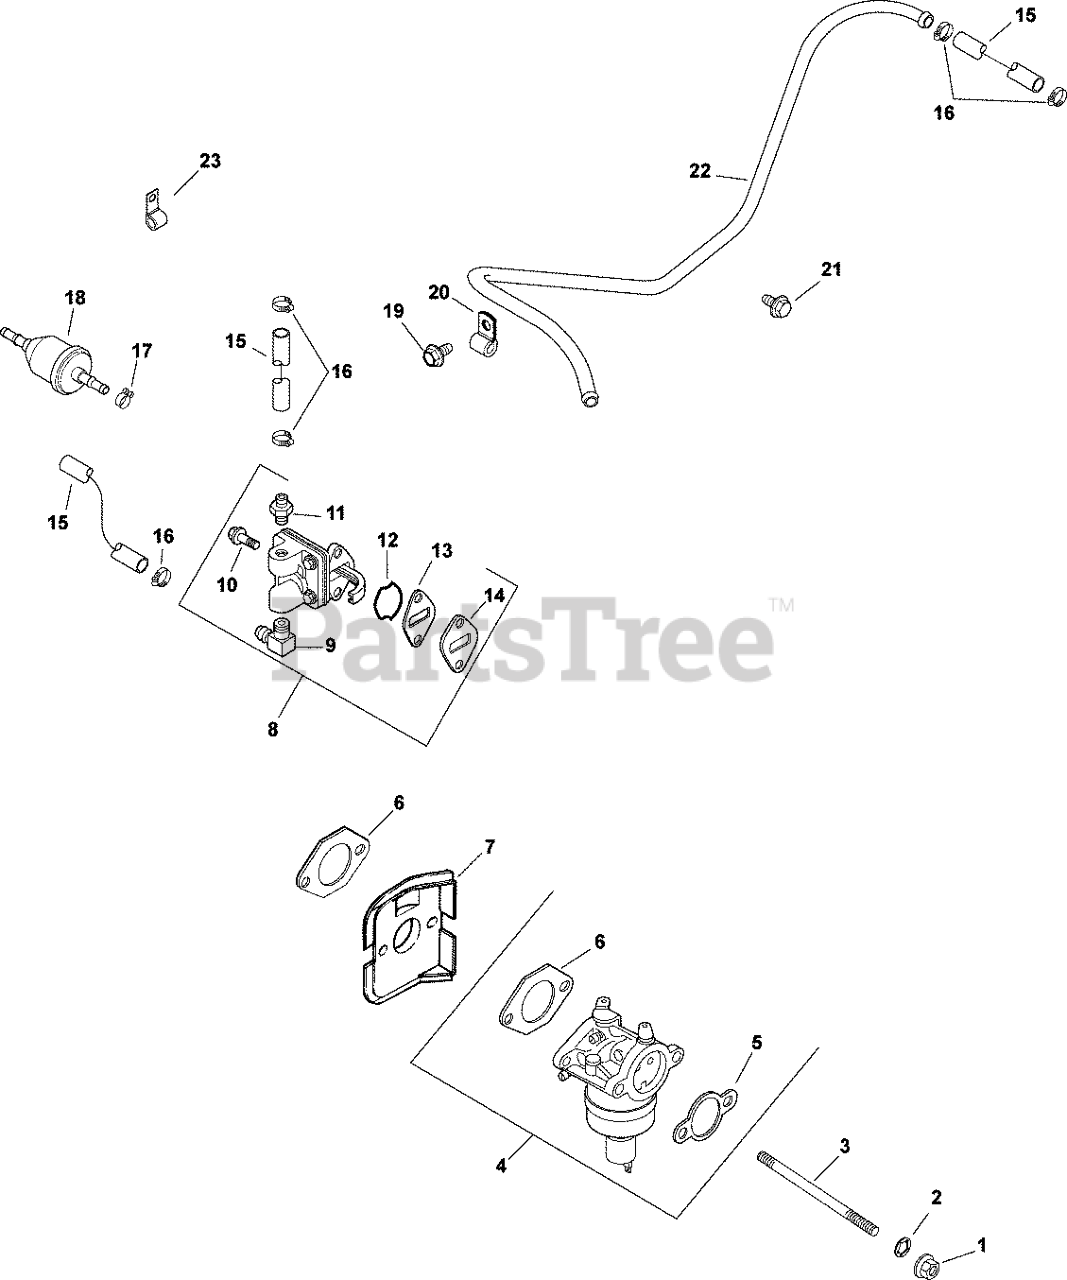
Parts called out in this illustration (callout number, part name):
1	NUT, FLG M6X1.0
2	WASHER, INT TOOTH LOCK 1/4"
3	STUD,M6X1.0X116
4	KIT, CARB W/GASKETS - USE 12 853 93-S
5	GASKET, AIR CLEANER BASE
6	GASKET, CARBURETOR
7	DEFLECTOR, HEAT
8	KIT, FUEL PUMP
9	CONNECTOR, 90 DEG. HOSE
10	SCREW, LBD SKT M6x1.0x20-(#25086403S)
11	KIT, STRAIGHT FITTING
12	O-RING, FUEL PUMP
13	GASKET, FUEL PUMP
14	SPACER, FUEL PUMP
15	HOSE,LW PERM.FUEL 24.00"-USE 25 111 81-S
16	CLAMP, HOSE (KM)-USE 25 237 31-S
17	CLAMP, BAND SPRING HOSE-(#2523737S)
18	FILTR,FUEL 75 MICRON (GRAVTY FEED)
19	SCREW, THRD FRM M5X0.8X10
20	CLIP, TUBE & WIRING (KM)
21	SCREW, FLG THD FRM M5X.8X10
22	LINE, FUEL
23	CLIP, CABLE
